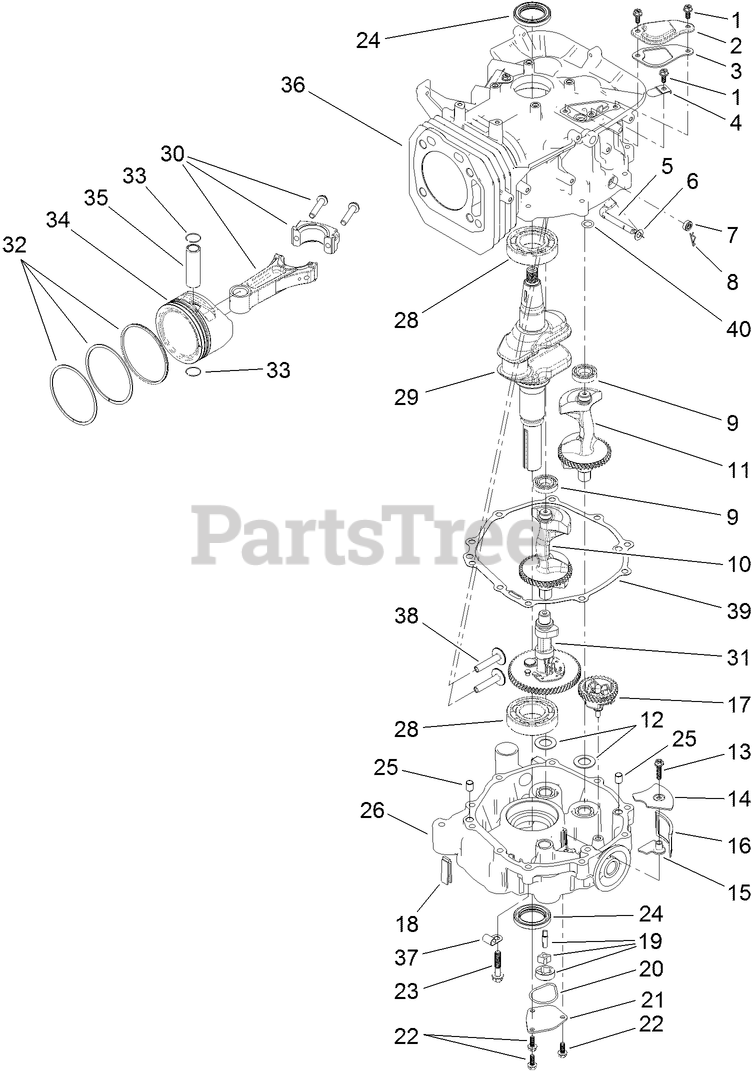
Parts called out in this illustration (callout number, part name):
1	SCREW-HHF
2	PLATE-BREATHER
3	GASKET-BREATHER
4	VALVE-REED
5	SHAFT-GOVERNOR
6	WASHER-PLAIN
7	SEAL-OIL
8	PIN-HAIR
9	BEARING-BALL
10	BALANCER-RH
12	WASHER
13	SCREW-HHF
14	COVER-STRAINER, OIL
15	PLATE-BAFFLE, OIL
16	STRAINER-OIL
17	GEAR-GOVERNOR
18	DEFLECTOR-OIL, RUBBER
19	OIL PUMP ASM
20	SEAL-PUMP, OIL
21	COVER-PUMP, OIL
22	SCREW-HHF
23	SCREW-HHF
24	SEAL-OIL
25	PIN-DOWEL
26	COVER-CRANKCASE
28	BEARING-BALL
29	CRANKSHAFT
30	CONNECTING ROD ASM
31	CAMSHAFT
32	RING SET
33	RING-RETAINING, PISTON PIN
34	PISTON
35	PIN-PISTON
36	CRANKCASE
37	CLAMP-J
38	LIFTER-VALVE
39	GASKET-CRANKCASE
40	O-RING
